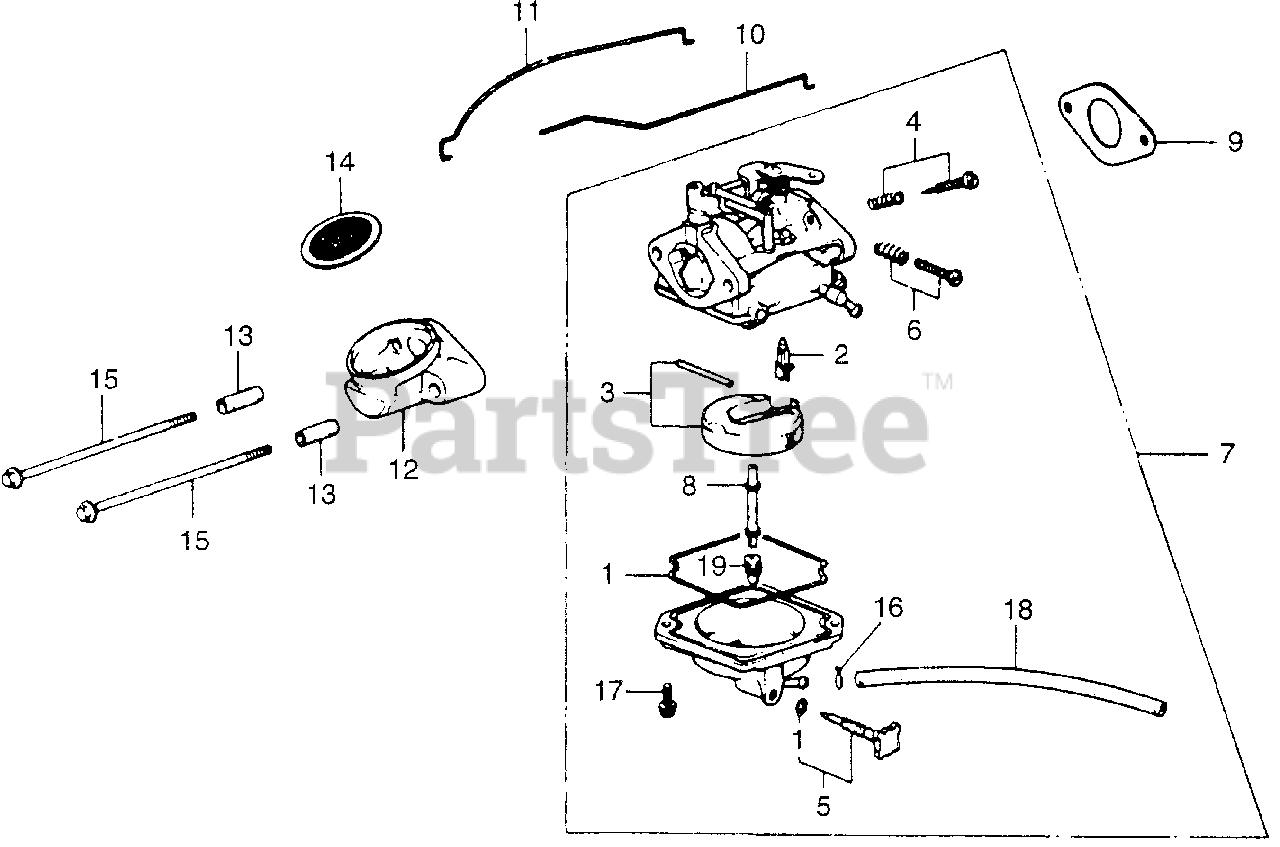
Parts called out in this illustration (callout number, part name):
1	GASKET SET
2	VALVE SET, FLOAT
3	FLOAT SET
4	SCREW SET A
5	SCREW SET, DRAIN
6	SCREW SET B (N/A: SEE ASSEMBLY)
7	CARBURETOR ASSY.
8	NOZZLE, MAIN (N/A: SEE ASSEMBLY)
9	GASKET, CARBURETOR
10	ROD, THROTTLE
11	ROD, CHOKE
12	GUIDE, AIR (NOT AVAILABLE)
13	COLLAR, DISTANCE
14	TRAP, FLAME
15	BOLT, FLANGE (6X97)
16	CLIP B7, TUBE
17	SCREW-WASHER (4X12)
18	BULK HOSE, FUEL (3.5X3000) (3.5X140)
19	JET, MAIN (#88)
19	JET, MAIN (#72)
19	JET, MAIN (#78)
19	JET, MAIN (#80)
19	JET, MAIN (#82)
